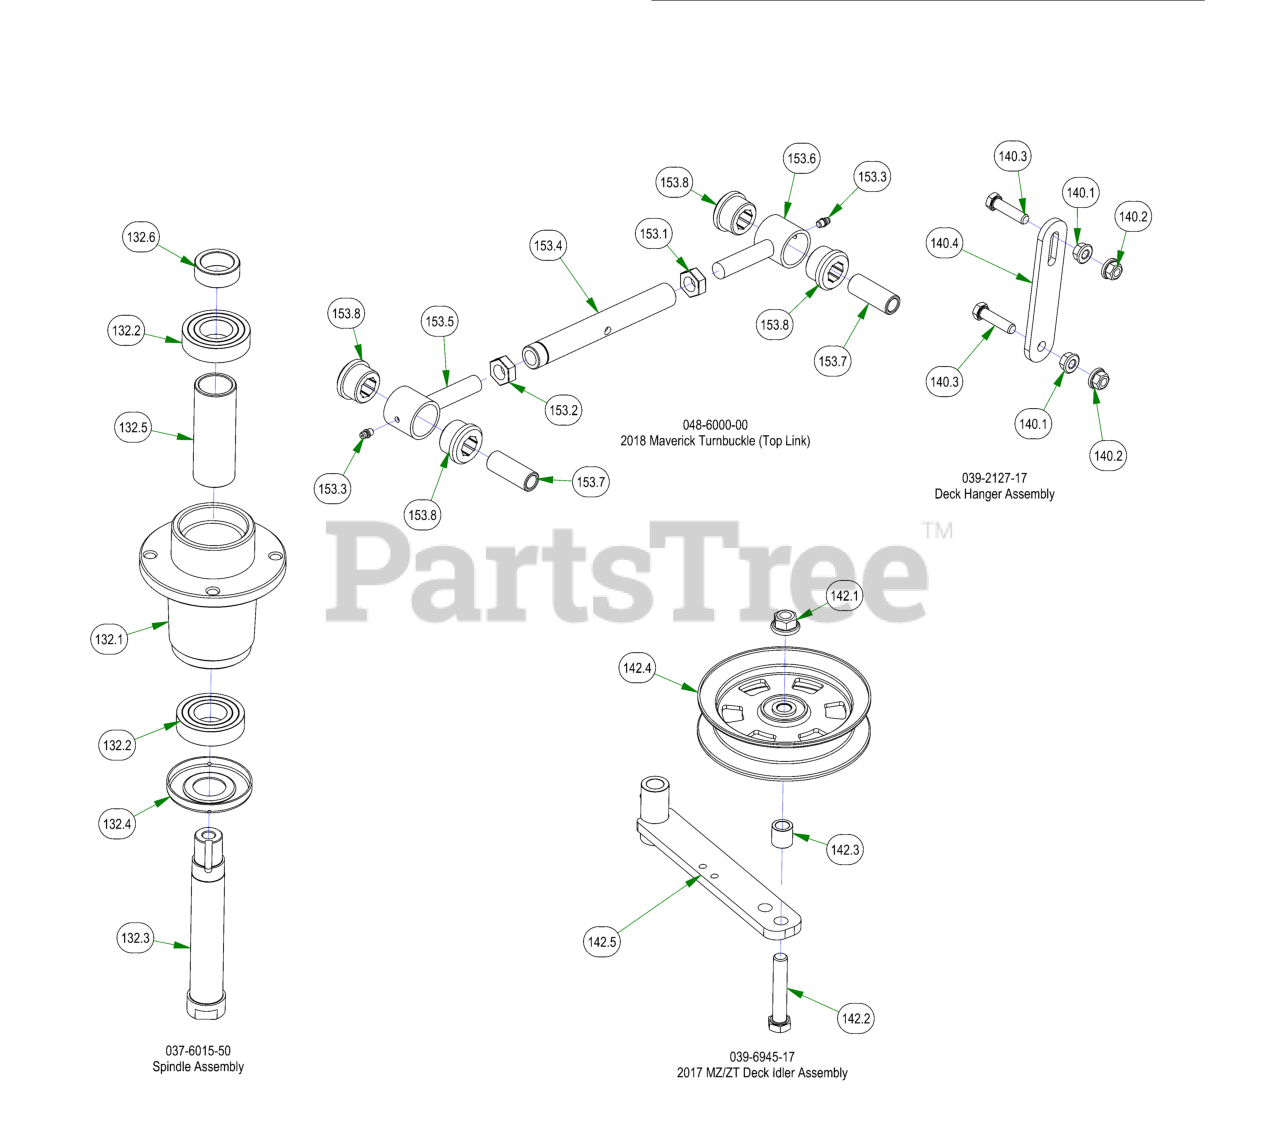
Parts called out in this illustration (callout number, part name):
132	Spindle Assembly
132.1	Spindle Housing
132.2	Bearing - 6206
132.3	Spindle Shaft
132.4	Spindle Dust Cap
132.5	Spindle Spacer
132.6	Locking Collar w/ 1/4"-20 Set Screw
140	Deck Hanger Assembly
140.1	3/8-16 HEX SERRATED FLANGE NUT HARD/ZINC
140.2	3/8-16 NYLON INSERT FLANGE LOCKNUT (GR.F) ZINC
140.3	3/8-16 X 1-1/2 HEX CAP SCREW (GR.5) ZINC
140.4	2017 MZ/ZT Deck Hanger
142	2017 MZ/ZT Deck Idler Assembly
142.1	1/2-13 NYLON INSERT FLANGE LOCKNUT ZINC
142.2	1/2-13 X 2-3/4 HEX CAP SCREW (GR.5) ZINC
142.3	Spacer 3/4 OD x 1/2 ID x 3\4 Length
142.4	5" Idler Pully
142.5	Deck Idler
153	2018 Maverick Turnbuckle (Top Link)
153.1	NUT, 5/8-18
153.2	NUT, 5/8-18LH
153.3	1/4-28 Grease Fitting
153.4	2018 Maverick Toplink Body
153.5	2018 Maverick Bushing Retainer Left-Handed
153.6	2018 Maverick Bushing Retainer Right-Handed
153.7	2018 Maverick Bushing Sleeve
153.8	2018 Maverick Bushing
